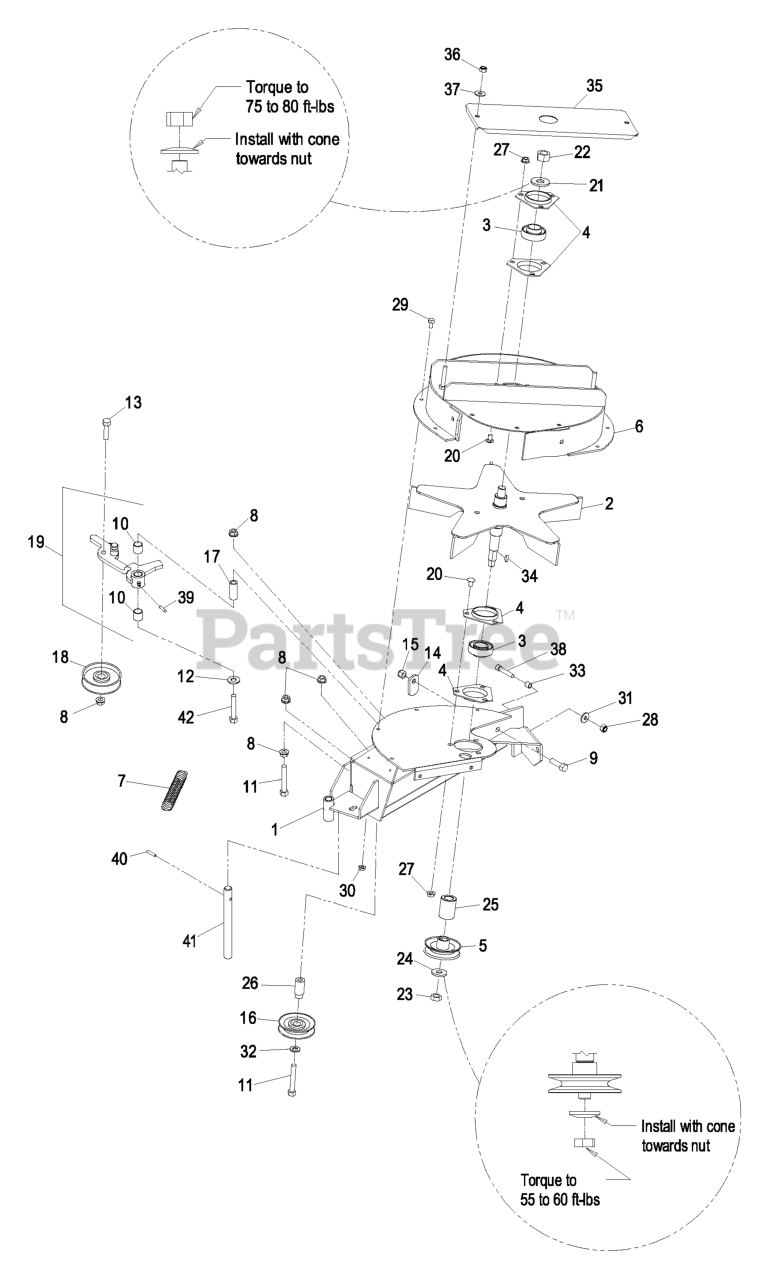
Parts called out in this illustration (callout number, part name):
1	WLD, BLOWER MOUNT
2	IMPELLER
3	BEARING
4	HOUSING-FLANGE
5	SHEAVE-BLOWER
6	ASM,UPPER HOUSING
7	SPRING-IDLER
8	NUT-HHF, WHIZ
9	SCREW-HH
10	BUSHING
11	BOLT-CARR
12	WASHER-FLAT
13	SCREW-HH
14	LATCH-CATCHER, GRASS
15	NUT-LOCK, NI
16	IDLER-INSIDE
17	BUSHING-PIVOT, IDLER
18	IDLER-FLAT
19	ASM, IDLER ARM - SERVICE
20	SCREW-CARR
21	WASHER-SPRING
22	NUT-HEX
23	NUT-JAM
24	WASHER-SPRING
28	NUT-HEX
29	SCREW-HH
31	WASHER-SPRING
32	WASHER-FLAT
33	BUSHING, LOCATOR
34	KEY-WOODRUFF
35	ASM, BEARING COVER
36	NUT-LOCK, NI
37	WASHER-FLAT
38	SCREW-HSH
39	FITTING-GREASE
40	PIN-ROLL
41	SHAFT-CATCHER, GRASS
42	SCREW-HSBH
